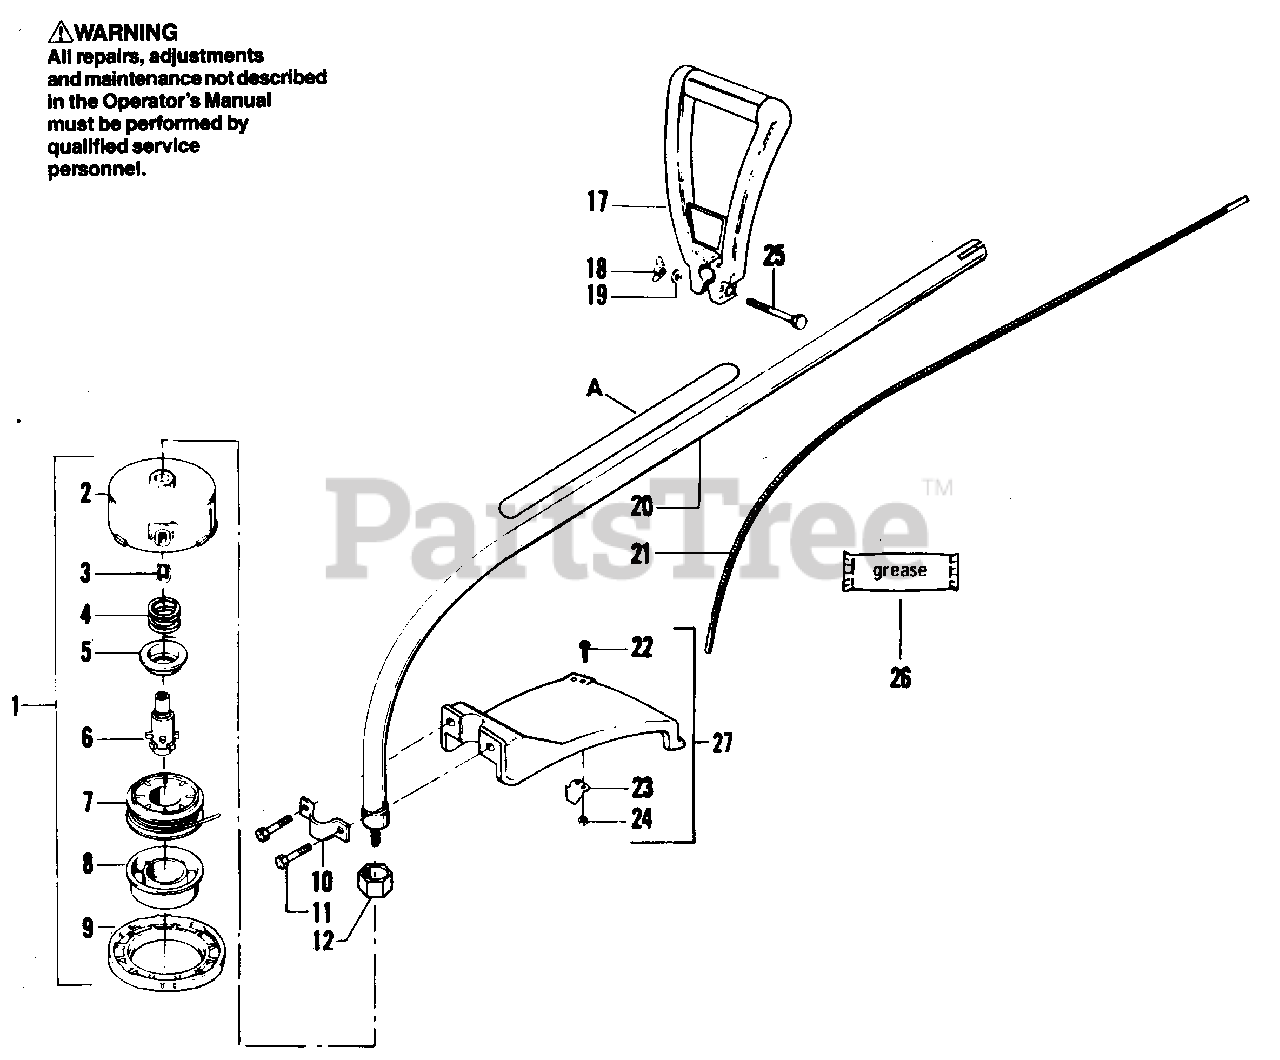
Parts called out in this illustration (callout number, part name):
1	Cutting Head Assembly (Incl. #2 - 9)
2	Hub w/Line Saver
3	Line Saver
4	Spring
5	Adaptor - Spring
6	Drive Gear
7	Spool w/Line
8	Release Button
10	Bracket - Shield
11	Screw, Shield - 1/4 - 10 x 1-1/8
12	Dust Cup
17	Assist Handle
18	Wing Nut - 1/4 - 20
19	Washer - 1/4 Flat
20	Drive Shaft Assembly
21	Flex Shaft Assembly
22	Screw - Line Limiter
23	Line Limiter
24	Nut - Line Limiter
26	Grease - Flex Drive Lube
27	Shield Assembly (Incl. #11, 22, 23 & 24)
A	Decal - Safety Label
